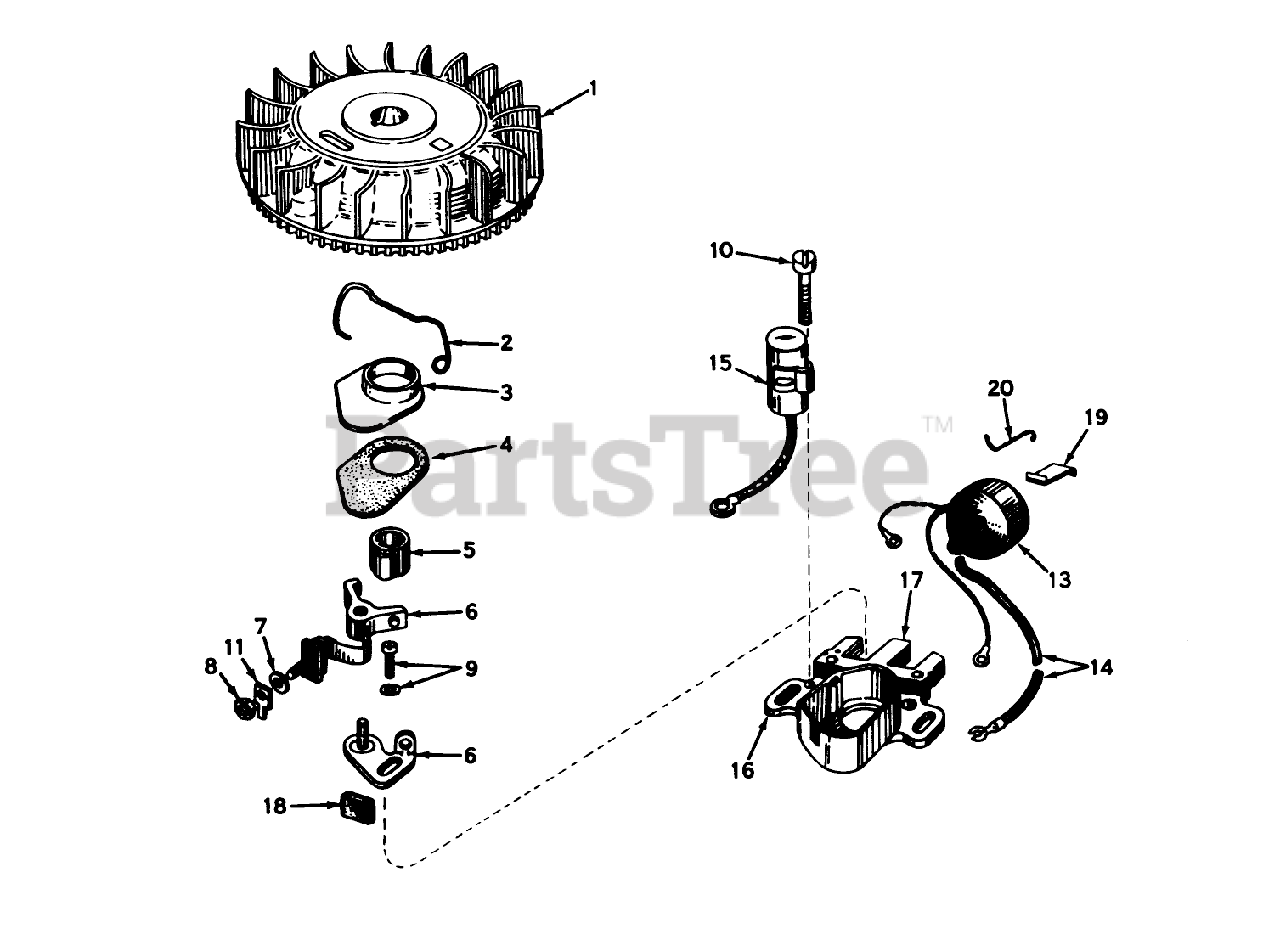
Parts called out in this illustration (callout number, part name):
1	FIywheel
2	Spring Breaker Box
3	Cover, Dust
4	Gasket Dust Cover
5	Cam, Breaker
6	Breaker Assy.
7	Washer
8	DECAL
9	Breaker Screw
10	Condenser Screw
11	Terminal, Ground
13	Coil Assy. (Incl. No. 12)
14	Wire, Lead
15	Condenser
16	Core Plate
17	Stator Assy., (Incl. Nos. 2, 3, 5 thru 14 16 thru 19)
18	Felt,Cam Wiper
19	Spring Coil Wedge
20	Clip, Coil
